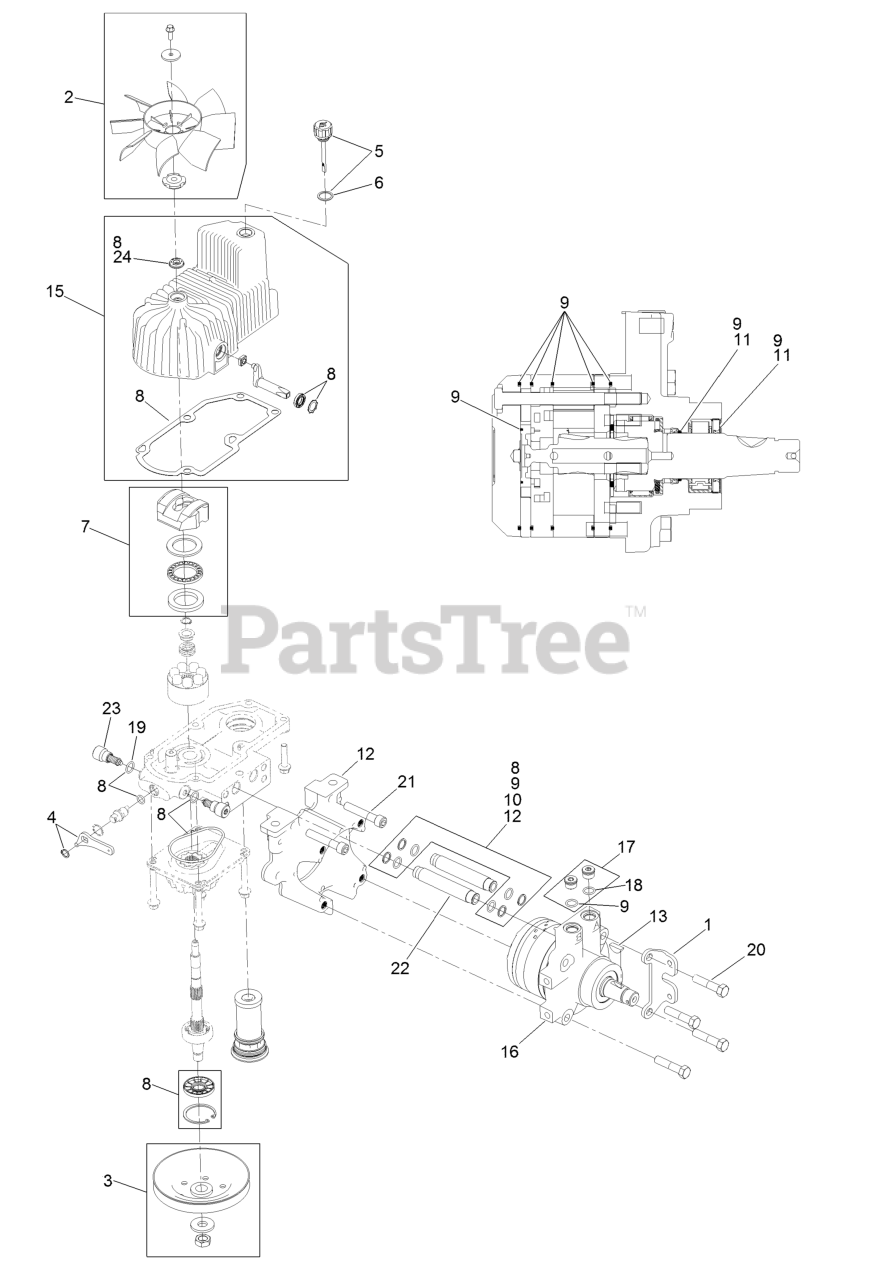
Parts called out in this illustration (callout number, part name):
1	MOUNT-SHOE, HORSE
2	FAN KIT
3	PULLEY KIT
4	HANDLE-BYPASS VALVE, HYDRO
5	DIPSTICK-HYDRO W/GASKET
6	GASKET-DIPSTICK, HYDRO
7	SWASH BLOCK KIT
8	PUMP SEAL KIT
9	MOTOR SEAL KIT
10	TUBE SEAL KIT
11	OUTPUT SHAFT SEAL KIT
12	NOSE CUP-UHT
13	KEY-WOODRUFF
15	HOUSING-HYDRO, RH
16	MOTOR-HYDRAULIC RH 240CC
17	MAGNETIC PLUGS SERVICE KIT
19	O-RING-CHECK VALVE
20	SCREW HH
21	SCREW-HSH
22	HYDRAULIC TUBE KIT
23	SHOCK VALVE, 12CC HYDRO
24	SEAL-FAN DRIVE
